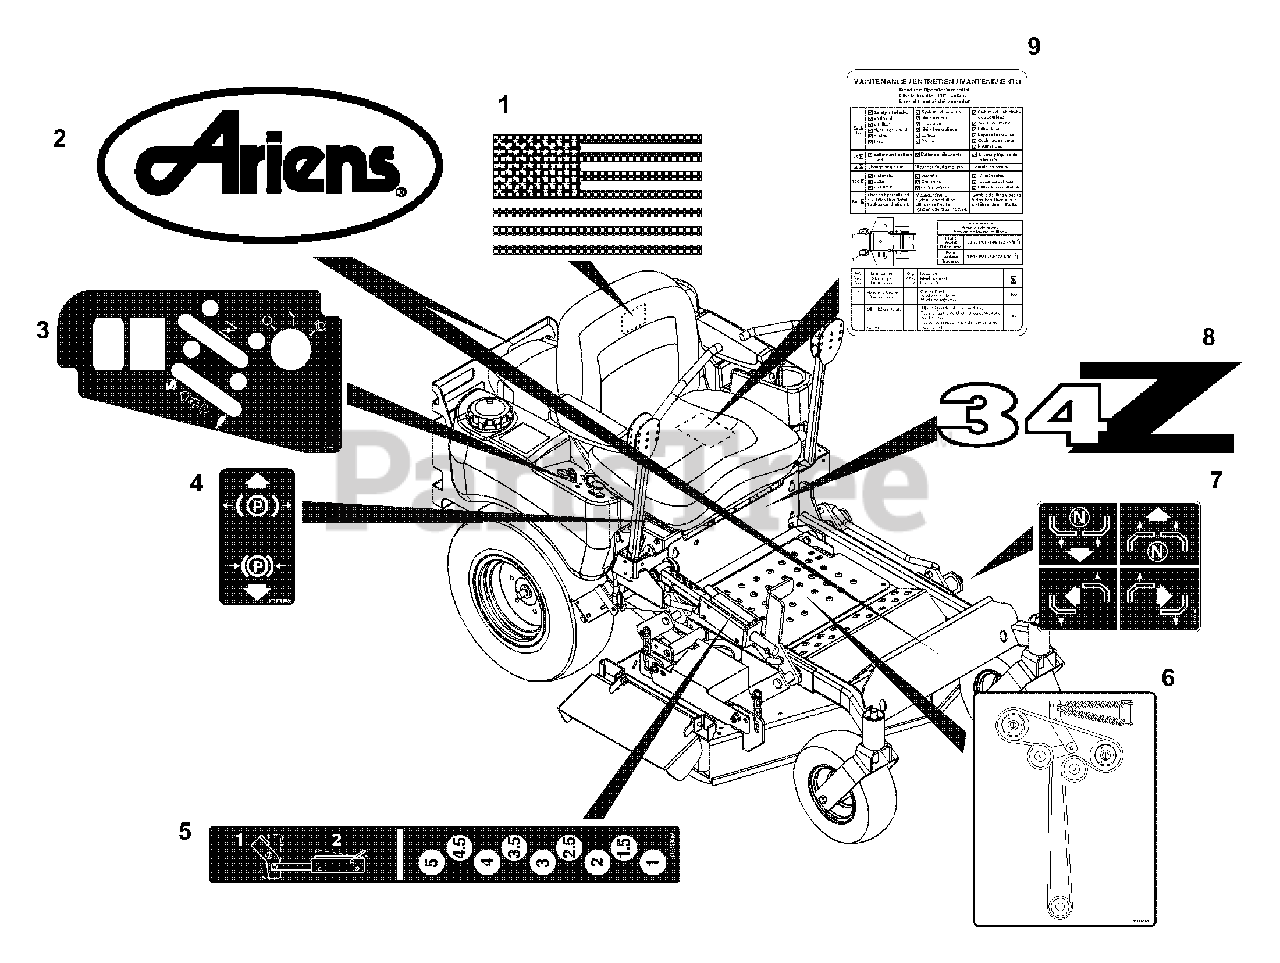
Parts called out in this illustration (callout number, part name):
1	DECAL, AMERICAN FLAG
2	DECAL, ARIENS
3	DECAL, CONTROL PANEL COMPACT Z
4	DECAL, PARKING BRAKE LEVER
5	DECAL, HEIGHT OF CUT COMPACT-Z
6	DECAL, BELT DIAGRAM COMPACT-Z
7	DECAL, INSTRUCTIONAL-STEERING
8	DECAL, STYLE COMPACT-Z
9	DECAL, MAINTENANCE INSTRUCTION
